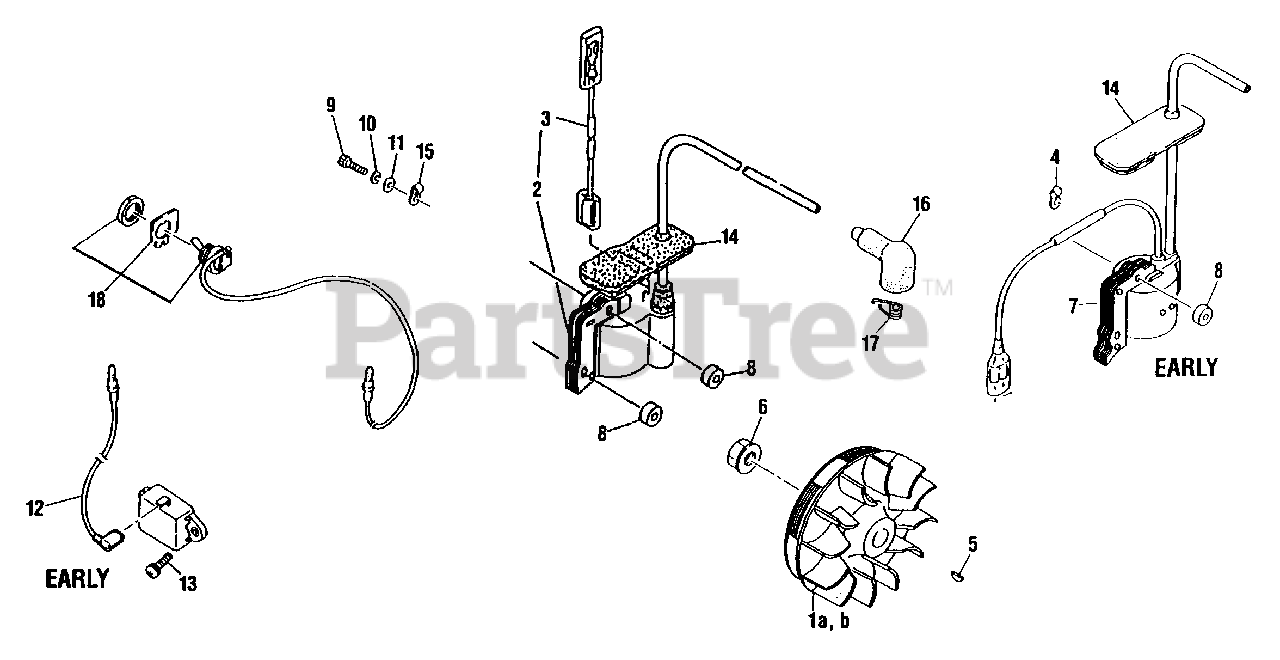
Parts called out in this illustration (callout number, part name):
1A	FLYWHEEL
1B	ROTOR ASSY
2	COIL
3	LEAD - IGNITION
4	CLAMP
5	KEY - 3X10
6	NUT - 8
7	COIL, IGNITION
8	INSULATOR
9	SCREW - 4X26
10	LOCKWASHER - 4
11	WASHER
12	WIRE
13	SCREW - 4X12
14	GROMMET
15	CLAMP
16	CAP, SPARK PLUG
17	TERMINAL, SPARK PLUG CAP
18	SWITCH
